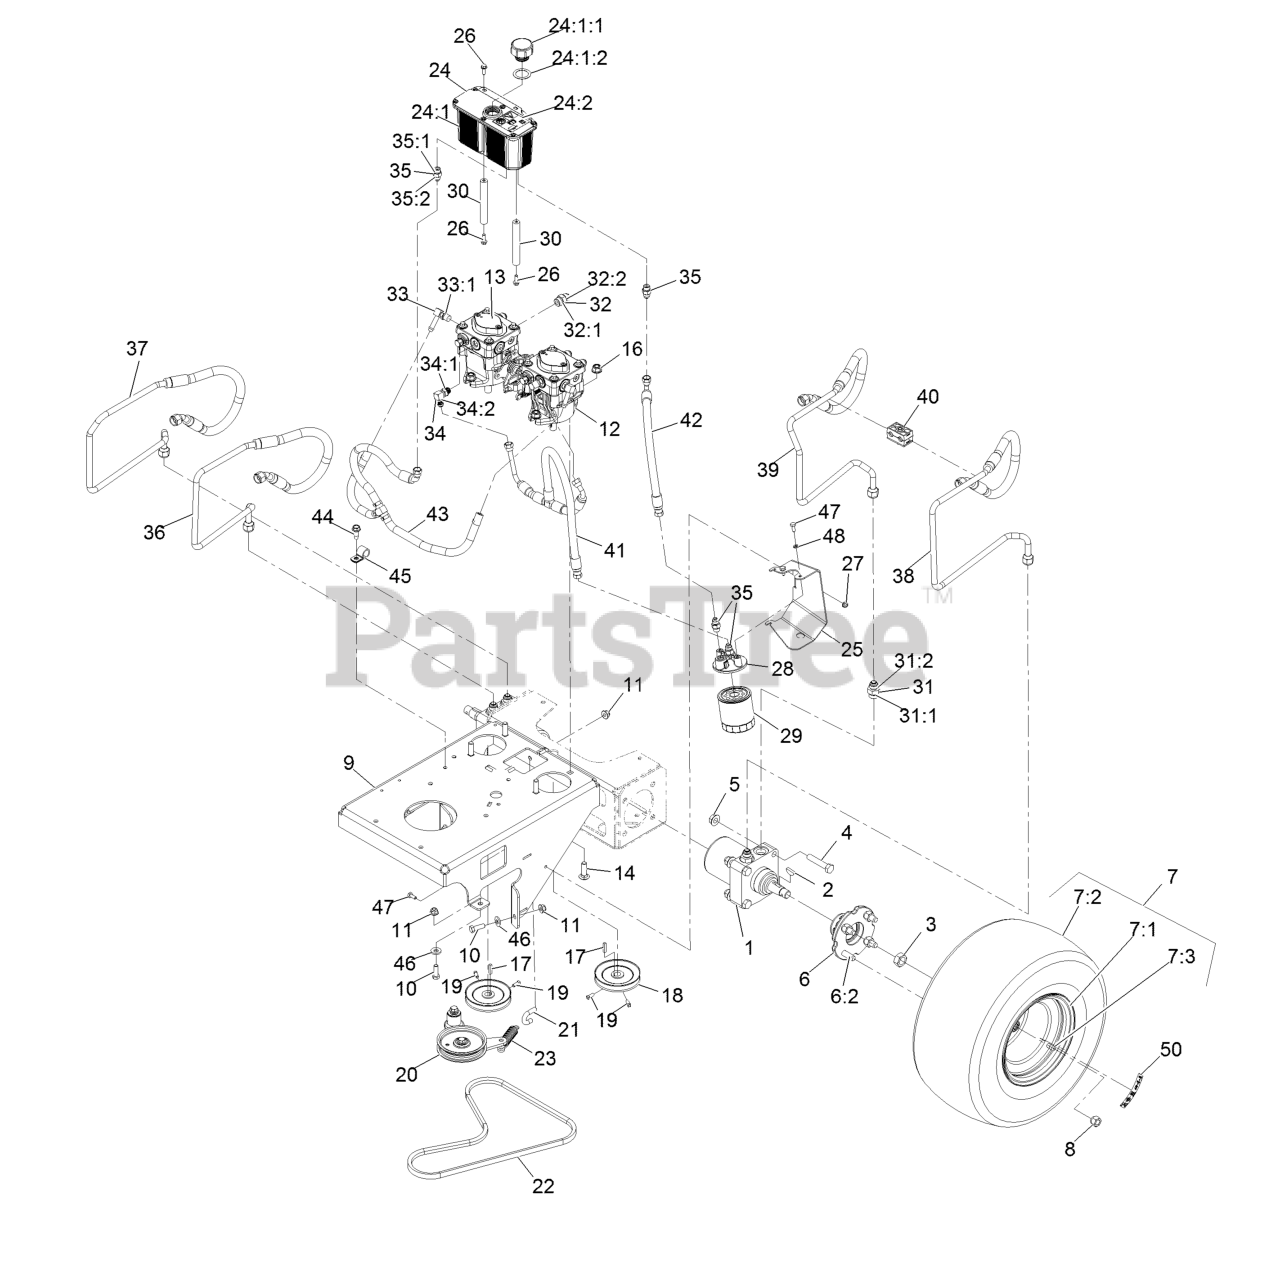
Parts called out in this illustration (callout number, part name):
1	HYD Motor ASM
2	Key-Woodruff
3	Nut-Motor, Wheel
4	Screw-HH 1/2-13 X 2 1/2
5	Nut-Hex 1/2-13 Side Lock
6	Wheel Hub ASM
6:2	Stud-Type, Drive
7	Wheel/Tire ASM
7:1	Rim-8 Inch
7:3	Stem-Valve
8	Nut-Lug 1/2-20
9	Base, Engine [red]
10	Screw-HH
11	Nut-Nyloc 3/8-16 Flg
12	Pump - Hydraulic
13	Pump-Hydraulic
14	Bolt-Carriage 7/16-14 X 1 1/2
16	Nut-HF, NI
17	Key-5Mm X 5Mm X 25Mm
18	Pulley-Pump
19	Setscrew-SQH 1/4-20 X 5/8
20	Pump Idler ASM
21	Anchor, Spring
22	Belt-V
23	Spring-Extension
24	ASM,Reservoir W/Decals
24:1	Reservoir-HYD
24:1:1	Cap-Reservoir, HYD
24:1:2	Gasket-Cap
24:2	Decal-Warning
25	Plate-Filter Mount
26	Screw-Hex Flange 1/4-20 X 3/4
27	Nut-Nyloc 1/4-20 Flg
28	Head-Filter
29	Element, Oil Filter
30	Rod-Reservoir Stand
31	Adapter-Straight
31:1	O-Ring
31:2	O-Ring-37 Flare #8
32	Adapter-Straight
32:1	O-Ring-SAE #8
32:2	O-Ring-37 Flare #8
33	Fitting-Barbed
33:1	O-Ring
34	Adapter-90deg
34:1	O-Ring-SAE #6
34:2	O-Ring-37 Flare #6
35	Adapter-Straight
35:1	O-Ring-SAE #6
35:2	O-Ring-37 Flare #6
36	Hose-Hardline
37	Hose-Hardline
38	Hose-Hardline
39	Hose-Hardline
40	Clamp, Stauff 212,7/12,7 W/Retainers
41	Hose-ASM Charge
42	Hose ASM-HYD LP 3/8X14.4
43	Hose ASM - HYD 3/8
44	Screw-Tapping
45	Clip-Loom 5/8
46	Washer-Spring Disc 3/8
47	Screw-HH 1/4-20 X 5/8
48	Washer-Lock 1/4 Heavy
50	Decal-Wheel Torque
